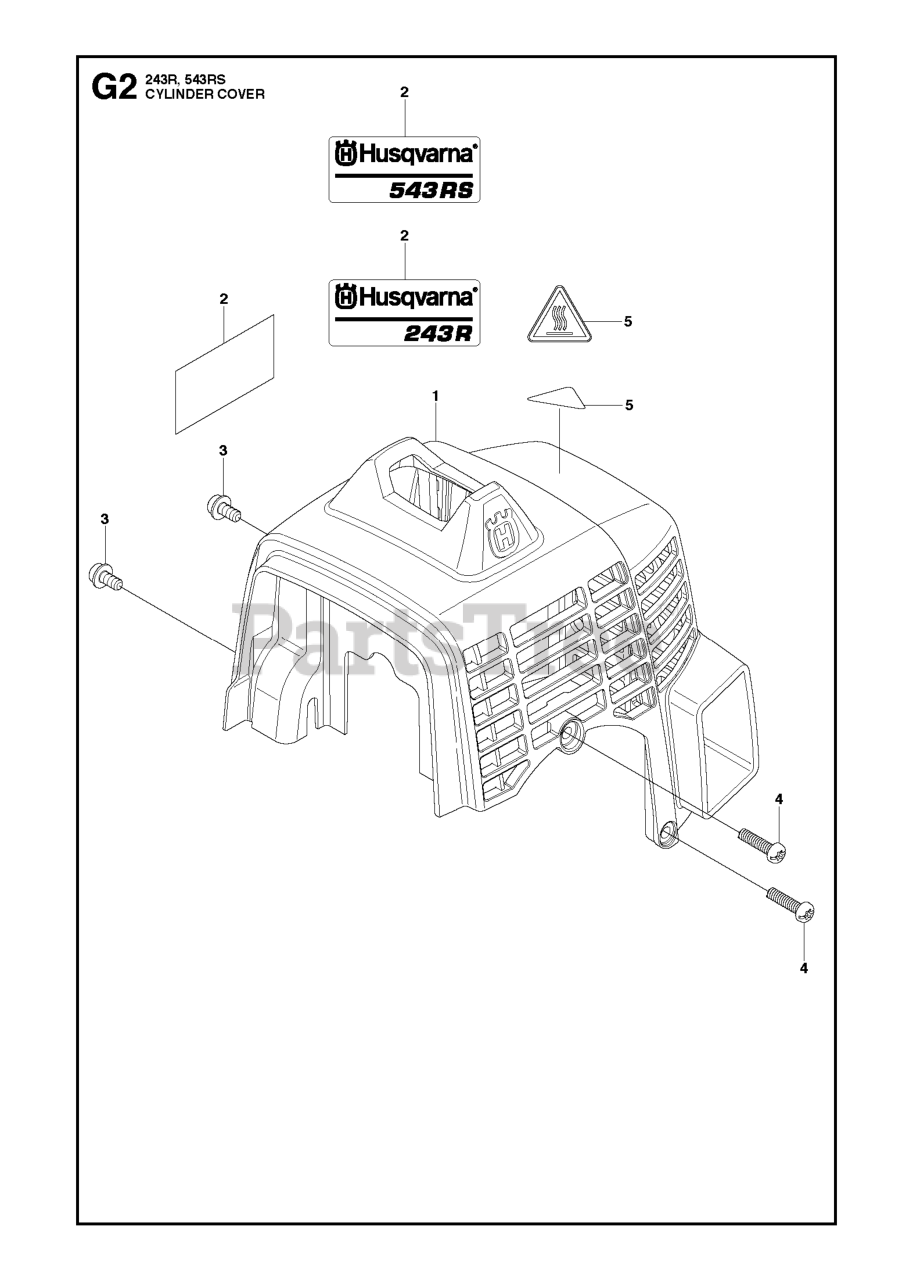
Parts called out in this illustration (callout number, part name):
1	COVER ENGINE
2	DECAL NAME GZ40N7
2	DECAL NAME
3	BOLT (RPLS T495051010-11)
4	SCREW, TORX (RPLS T4970-52001)
5	LABEL HOT CAUTION
